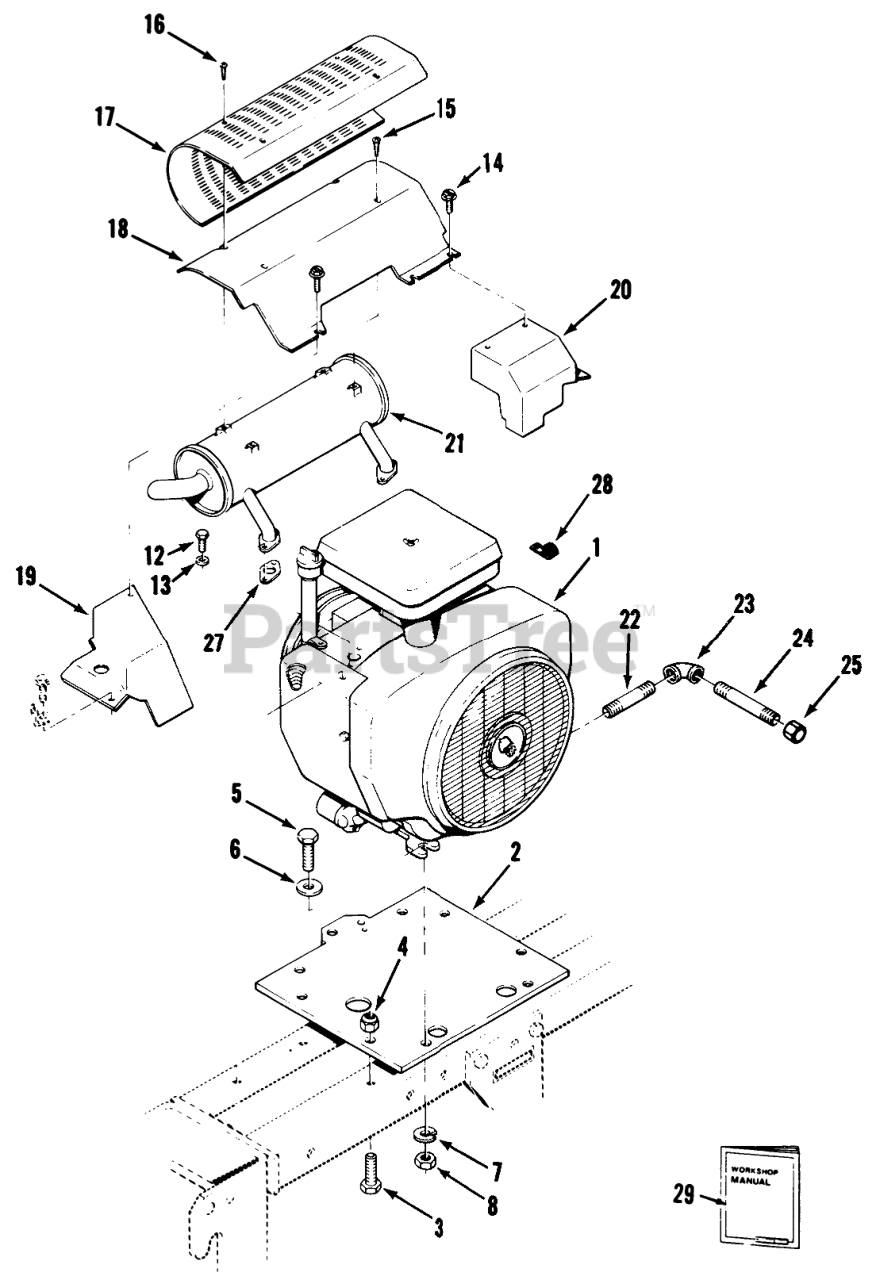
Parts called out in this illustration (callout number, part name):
1	Engine-TORO Power Plus-20HPP220G-I/10955C 520-H
2	PLATE-ENGINE B
3	SCREW-HH
4	NUT-LOCK, NI
5	SCREW-HH
6	WASHER-FLAT
7	LOCKWASHER
8	Nut
12	SCREW-HH
13	WASHER-LOCK
14	Bolt
15	Screw
16	SCW 10-24 STAINLESS
17	SHIELD
18	Air Deflector
19	LH Exhaust Cover
20	RH Exhaust Cover
21	MUFFLER-EXHAUST
22	Pipe
23	ELBOW 3/8 90 DEG
24	PIPE-NIPPLE 3/8 X 4"
25	Cap
27	Exhaust Gasket
28	CLIP
29	Manual-Toro Power Plus Service
